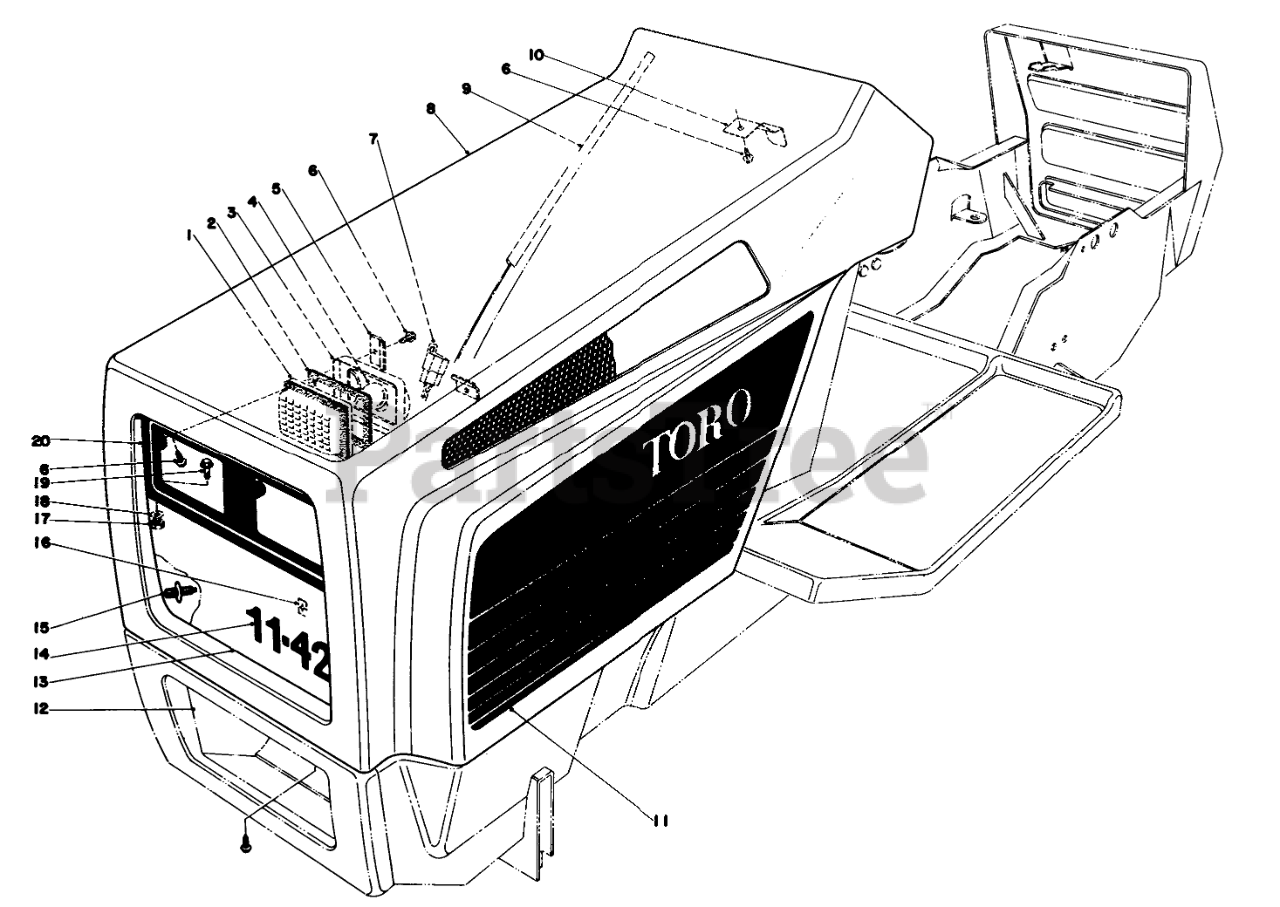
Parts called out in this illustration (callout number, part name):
1	14 Lens
2	Gasket Lens
3	Lamp-Green
5	HEADLIGHT CLAMP
6	Screw
7	CONNECTOR BODY
9	RUBBER EXT SEAL
10	SPRING LATCH
11	Decal Hood LH.
12	LOWER GRILLE
13	HEADLIGHT GRILLE
14	GRILLE NAMEPLATE
15	HINGE BRKT STUD
17	NUT-LOCK, SIDE
18	WASHER-FLAT
19	SCREW-SHWH
20	HEADLIGHT PANEL B
